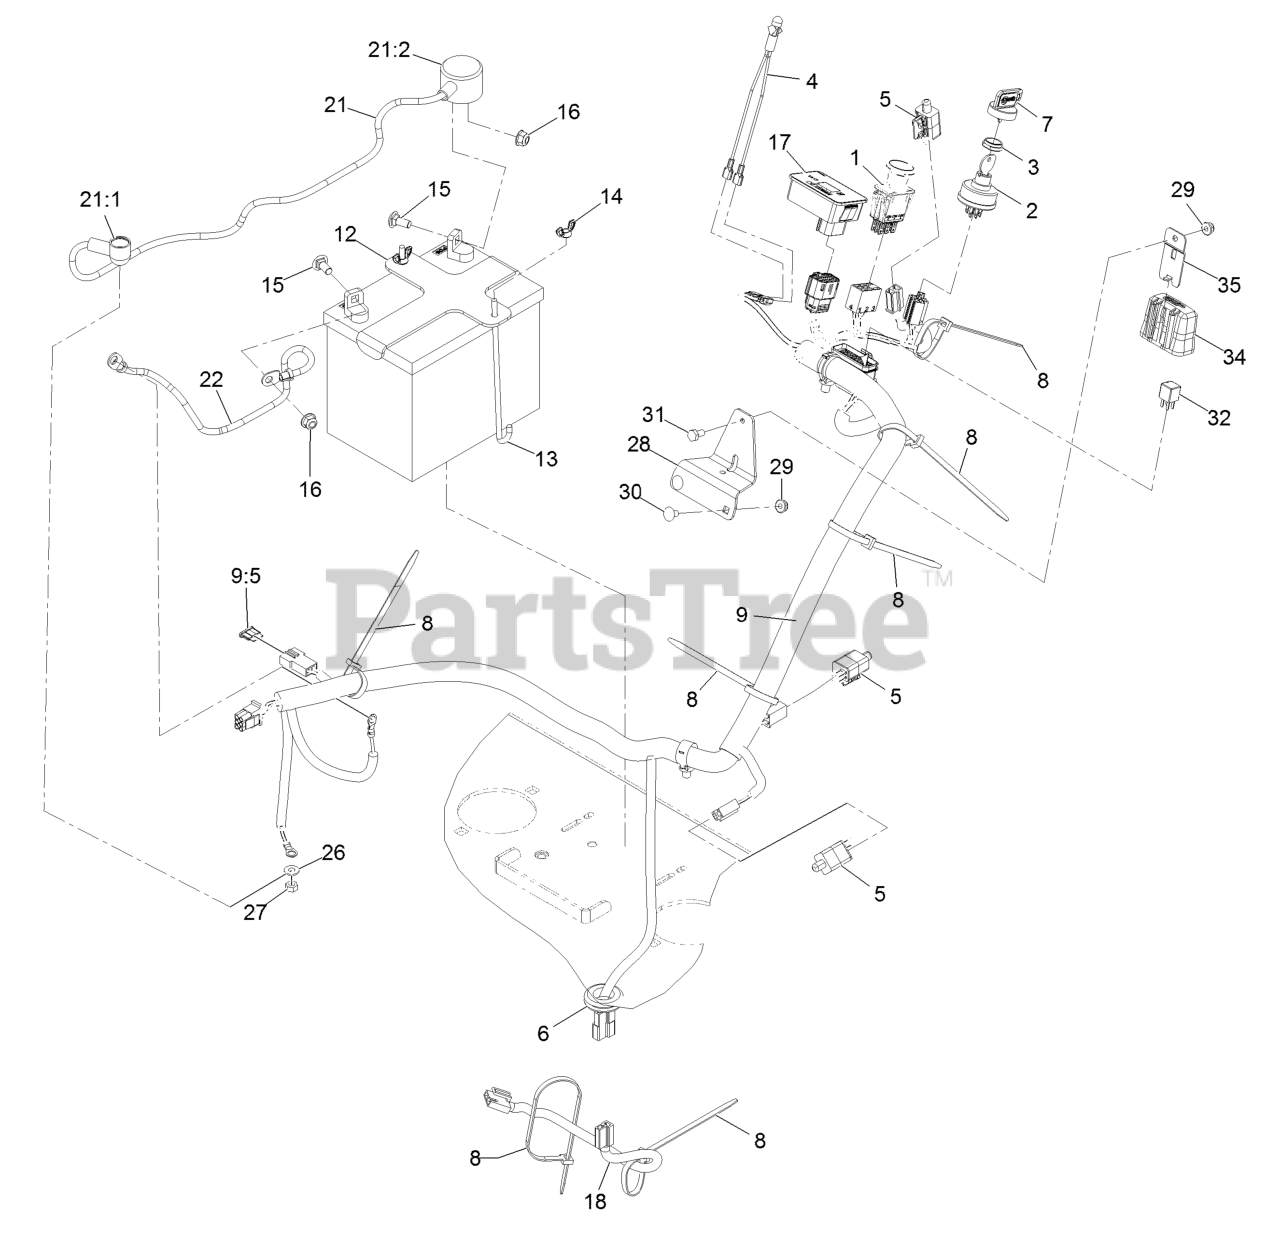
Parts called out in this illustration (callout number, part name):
1	Switch-PTO
2	Switch, Key Start
3	Nut-Ignition
4	Indicator-Red LED
6	Grommet
7	Key-Exmark Logo
8	Tie-Cable 7 15/16 (Large)
9	Harness-Wire
9:5	Fuse-Blade Type, 20 Amp
12	Bracket, Battery Hold Down
13	Bolt-Holddown
14	Wingnut-Nyloc 1/4-20
15	Bolt-Carriage 5/16-18 X 3/4
16	Nut-Nyloc 5/16-18 Flg
17	Module-Hour Meter
18	Harness-Clutch Pigtail
21	Positive Battery Cable ASM
21:1	Insulator-Solenoid
21:2	Insulator-Battery
22	Cable-Battery, Negative
26	Washer-Flat
27	Nut-Hex
28	Bracket-Mounting, Fuseblock
29	Nut-Nyloc 1/4-20 Flg
30	Bolt-Carriage 1/4-20 X 1/2
31	Screw-HH 1/4-20 X 1/2
32	Relay-Micro
34	Cover-Block, Fuse
35	Clip-Mounting
